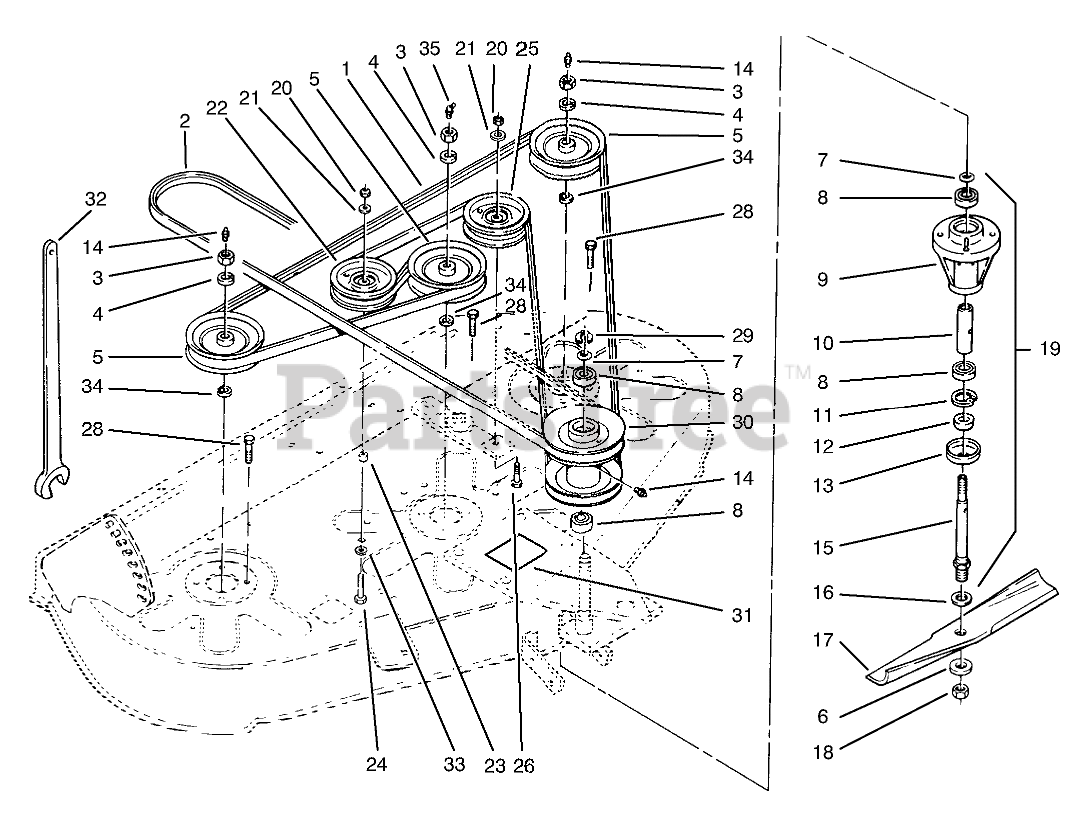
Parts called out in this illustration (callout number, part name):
1	V-BELT
2	V-BELT
3	NUT-JAM
4	WASHER-LOCK
5	PULLEY-SPINDLE
6	WASHER-FLAT
7	O RING
8	BEARING-BALL
9	HOUSING-SPINDLE
11	RING-RETAINING
12	SPACER-BLADE
13	CUP-SPINDLE
14	FITTING-GREASE
15	SHAFT-SPINDLE
16	Washer
17	SERV ASS'Y-BLADE PKG
18	NUT-JAM
19	ASSY SPINDLE 42-48MW
20	NUT-LOCK, NI
21	WASHER-FLAT
22	PULLEY-IDLER, FLAT
23	SPACER
24	SCREW-HH
25	PULLEY-FLAT IDLER
26	SCREW-HH
28	SCREW-HH
29	RETAINING RING
30	PULLEY-COUNTER SHAFT
31	DECAL-BELT INSTALL
32	Spindle Wrench
33	WASHER
34	WASHER-FLAT
35	FITTING-GREASE
